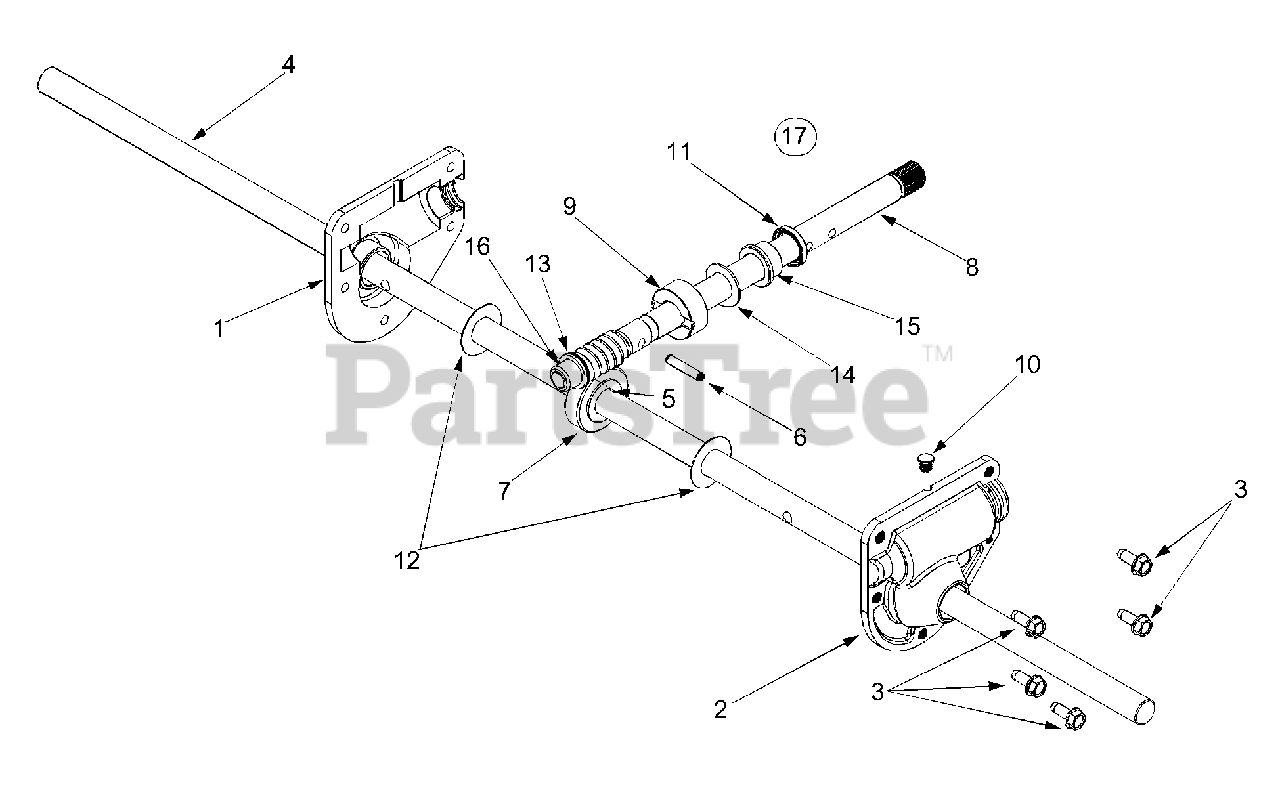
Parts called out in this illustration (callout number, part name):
1	Housing RH
2	Housing LH
3	Hex Screw 1/4-20 x .75
4	Spiral Axle 22"
4	Spiral Axle 24"
4	Spiral Axle 26"
6	Pin-Spiral
7	Gear-Worm
8	Shaft-Worm
9	Collar-Thrust
11	Seal-Oil
12	Washer-Flat
13	Washer-Flat
14	Washer-Flat
15	Bearing-Flange
16	Bearing-Flange
17	Ass’y Complete 22"
17	Ass’y Complete 24"
17	Ass’y Complete 26"
